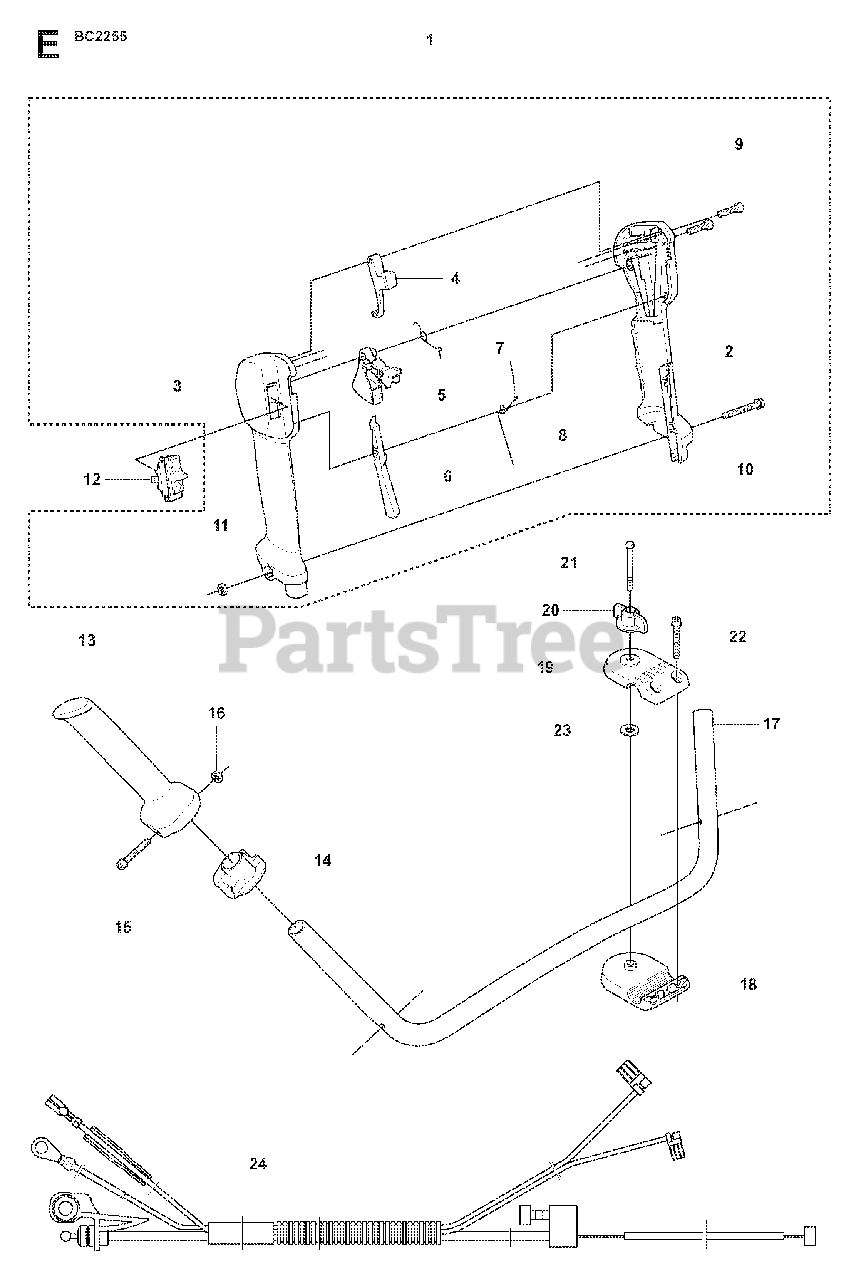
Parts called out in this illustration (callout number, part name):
1	THROTTLE HANDLE ASSY
2	HANDLE HALF RIGHT
5	TRIGGER
6	TRIGGER SAFETY
10	%SCREW
12	STOP BUTTON
16	NUT M6M M5
17	HANDLE
18	HANDLE BRACKET
19	HANDLE BRACKET
21	%SCREW
